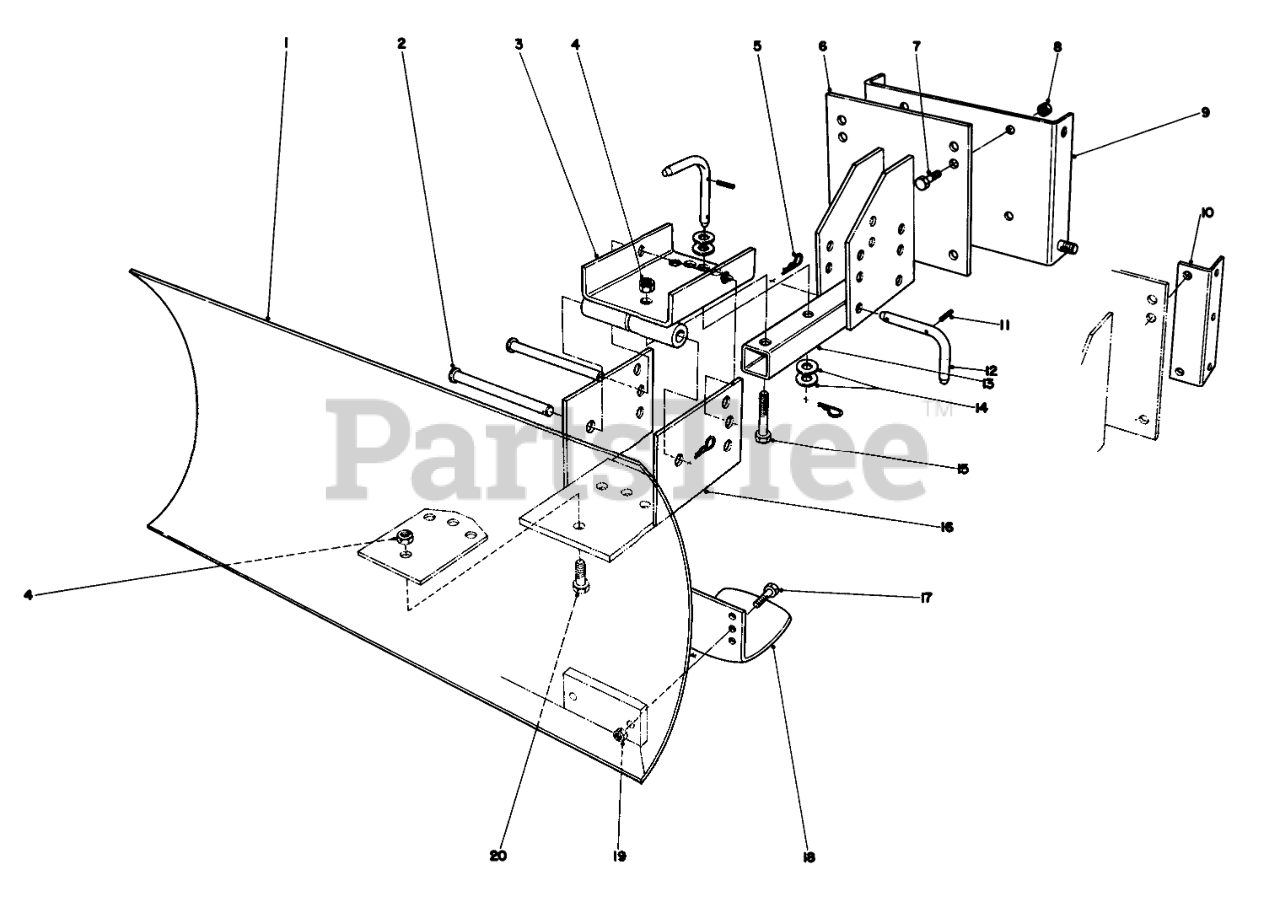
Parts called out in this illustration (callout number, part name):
1	Blade
2	PIN-CLEVIS
3	Swivel Bracket
4	1/2-13 CONELOCK NUT
5	PIN-HAIR
6	Mounting Plate
7	SCREW-HH
8	NUT-LOCK, CONE
9	Mounting Plate (Used with 826 & 1132 Units only)
10	Mounting Rail (used with 421 units only)
11	PIN-SPRING
12	Pivot Pin (Incl. Ref. #11)
13	Blade Tongue
14	WASHER-FLAT
15	SCREW-HH
16	Blade Adjustment
17	SCREW-HH
19	NUT-LOCK, CONE
20	SCREW-HH
